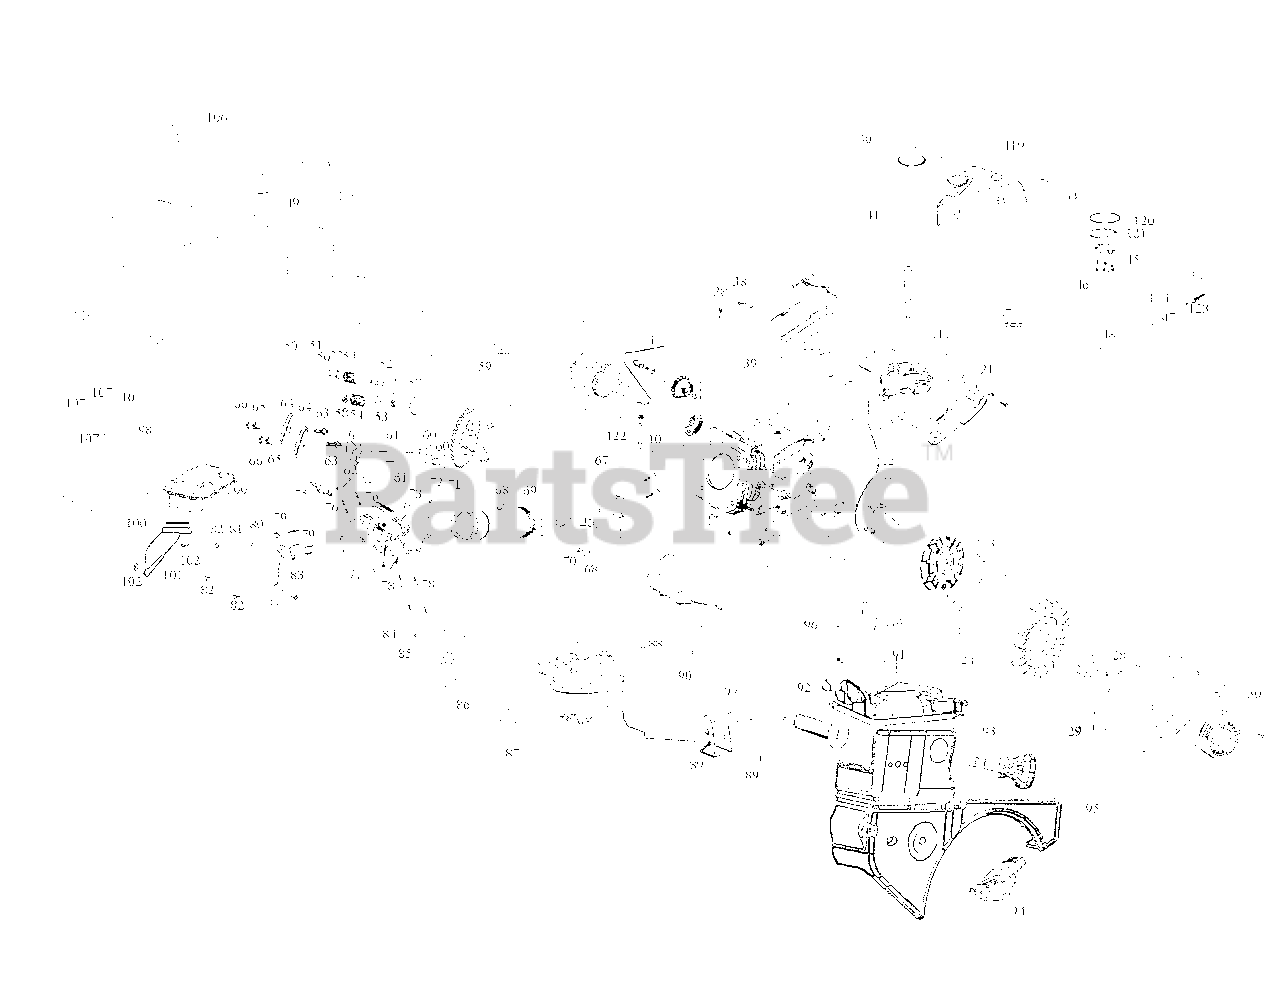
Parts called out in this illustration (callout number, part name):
1	Crankcase Cover
2	Oil Seal
4	Bolt
5	Dowel Pin
6	Crankcase Cover Gasket
6	Case Cover Gasket
7	Crankshaft Assembly
8	Governor Assembly
9	O-Ring
9	O-Ring - Governor Arm
10	Pin Lock
11	Bearing
14	Electric Starter
15	Oil Drain Pipe
17	Ignition Coil
28	Fan Cover Complete
30	Recoil Starter Assembly
35	Governor Spring
36	Throttle Return Spring
37	Governor Rod
40	Dipstick
41	Dipstick Tube
42	Cover - Engine/Dipstick
43	Fuel Cap Complete
44	Dowel Pin
45	Fuel Filter
46	Fuel Tank
47	Fuel Line Clamp
48	Fuel Line
49	Muer Shroud
50	Oil Filler Plug
50	Oil Fill Plug
51	O-Ring - Oil Filler Plug
51	O-Ring
52	Exhaust Valve
54	Valve Spring
55	Valve Spring Retainers - Exhaust
56	Exhaust Valve Adjuster
57	Intake Valve
58	Valve Spring Retainer- Intake
59	Camshaft Assembly
60	Valve Lifter (Tappet)
61	Push Rod
62	Push Rod Guide
63	Rocker Arm Studs
64	Rocker Arm
65	Pivot Adjusting Nut
66	Rocker Arm Lock Nut
67	Connecting Rod Assembly Complete
68	Piston Pin Clip
72	Dowel Pin
74	Muffler Gasket
75	Spark Plug
77	Cylinder Head
78	Muffler Stud
80	Head Cover Gasket
80	Valve Cover Gasket
84	Carb Insulator Gasket
84	Carburetor Insulator Plate Gasket
84	Carb Insulator Plate Gasket
85	Carburetor Insulator
85	Carburetor Insulator Plate
86	Carburetor Gasket
87	Primer
88	Carburetor Assembly
91	Air Filter Heating Pipe Cover
92	Ignition Switch
93	Ignition Key
94	Choke Lever
95	Engine Shroud
97	Air Filter Gasket
98	Muffler Shield
100	Paper Gasket
105	Oil Drain Bolt
105	Drain Bolt
112	Oil Drain Washer
112	Oil Drain Plug Washer
115	Choke Push Rod
120	Packing ( Gasket )
121	Clip ( Gasket Retainer )
122	Governor Arm Shaft
123	Fuel Tank Nipple
